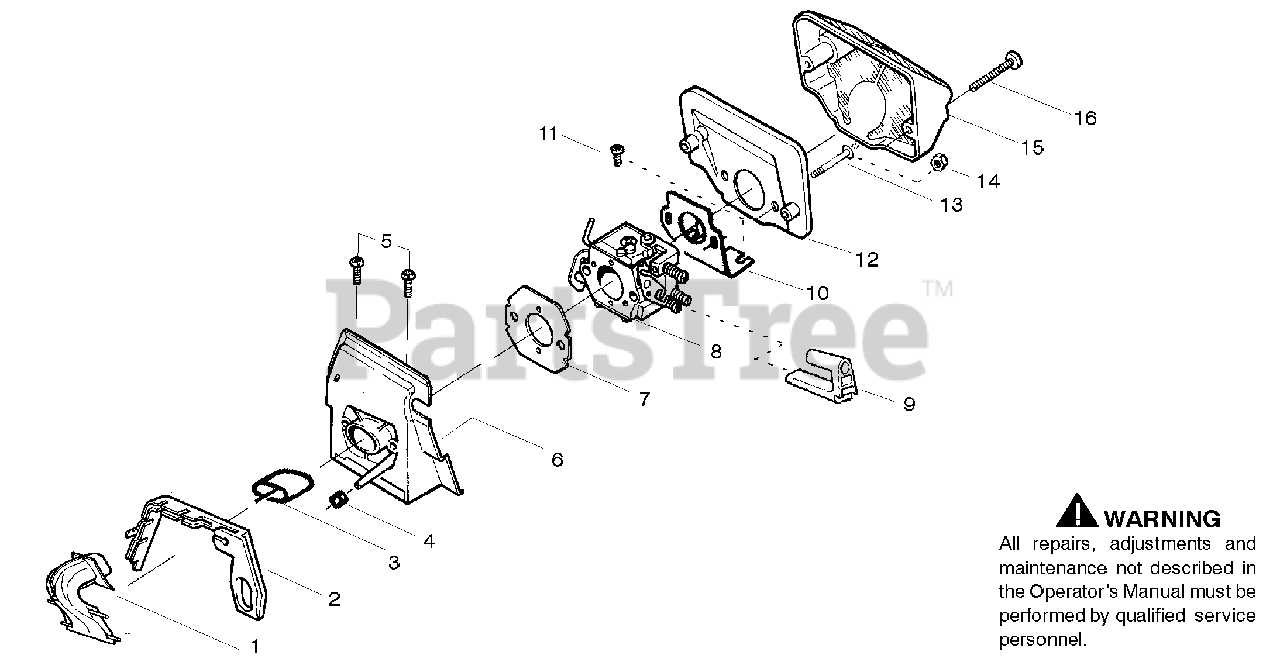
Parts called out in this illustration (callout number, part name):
1	Assy-Turbo Air Cleaner
2	Seal - Turbo Clean
3	Sleeve-Intake
4	Seal-Impulse
6	Adapter - Carb.
7	Gasket-Carburetor
8	Carburetor
9	Grommet-Final
10	Plate - Support
12	Air Filter - Bottom
13	Stud - Carb.
15	Air-Filter - Top
